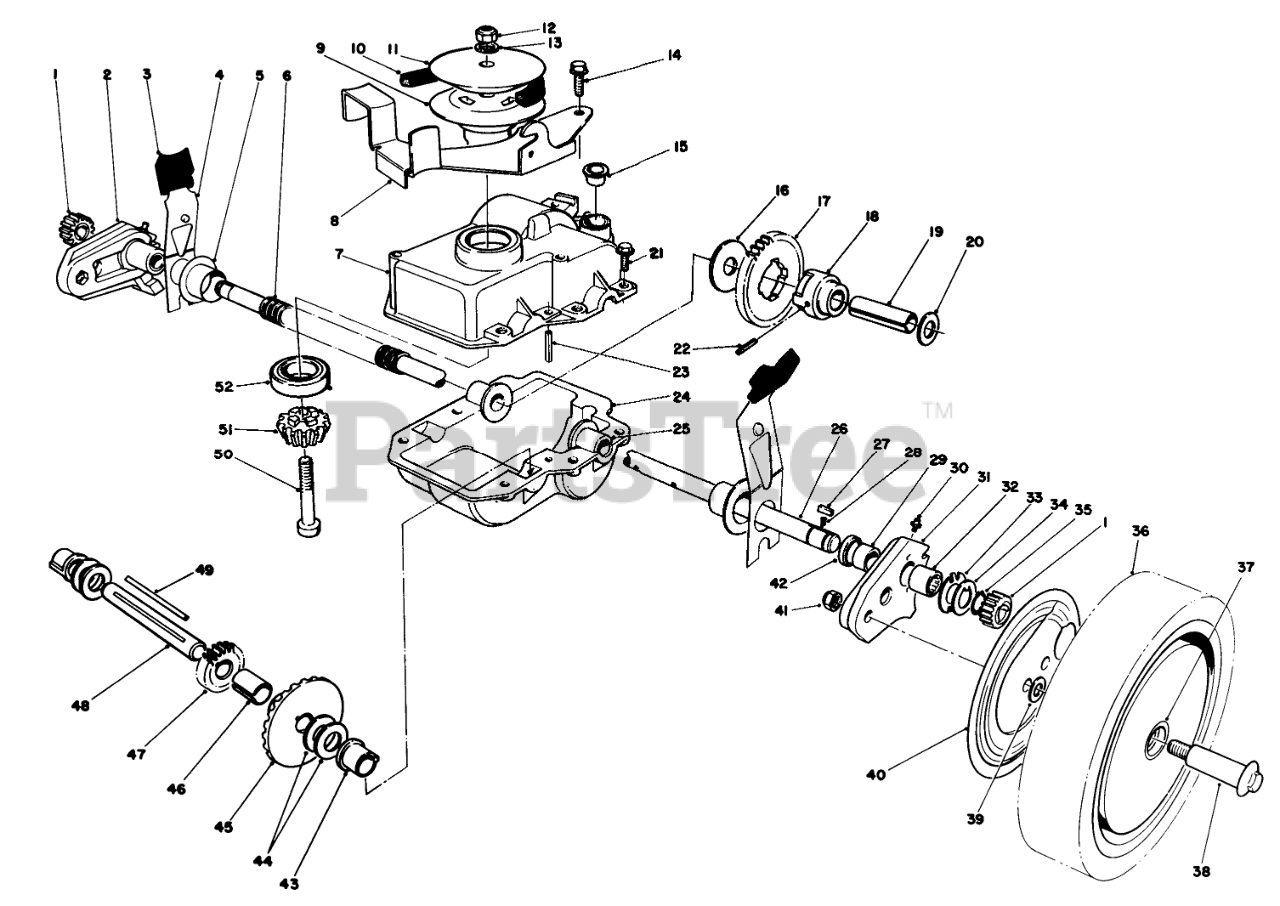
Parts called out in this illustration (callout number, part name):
1	GEAR-PINION
2	Pivot Arm Assembly-R.H. (Incl. Ref. #29, 30, 32 & 42)
3	KNOB-ARM
4	SPRING ARM ASM SP
5	CAP-END
6	CONDUIT-CONVOLUTED, SPLIT
7	Case-Upper
8	BELT GUIDE BRKTB
9	PULLEY-LOWER HALF
10	V-BELT
11	PULLEY-UPPER HALF
12	NUT-LOCK, NI
13	WASHER-FLAT
14	SCREW
15	Caplug
16	WASHER
17	GEAR-42T
18	DRIVE ADAPTER
19	Spacer-Output Shaft
20	WASHER-PLAIN
21	SCREW-HWHTF
22	COIL PIN.156 X 1.125
23	ROLL PIN 3/16 X 1 IN
24	LOWER GEAR CASE CAST
25	Bushing-Output Shaft
26	Output Shaft
27	KEY RECTANGULAR
28	SPRING-COMPRESSION
29	BUSHING
30	FITTING-GREASE
31	Pivot Arm Assembly-L.H. (Incl. Ref. #29, 30, 32 & 42)
32	BEARING-ROLLER
33	INNER THRUST WASHER
34	WASHER-THRUST, OUTER
35	RING-RETAINING
36	Wheel, Tire & Gear Assembly (Incl. Ref. #37)
37	BUSHING
38	WHEEL BOLT
39	WASHER
40	WHEEL COVER
41	NUT-LOCK
42	SEAL-OIL
43	BUSHING
44	WASHER-THRUST
45	BEVEL GEAR
46	Spacer-Short Shaft
47	GEAR-14T
48	INTERMEDIATE SHAFT
49	Key Square
50	Screw-Socket Hd
51	BEVEL PINION
52	BEARING-BALL
